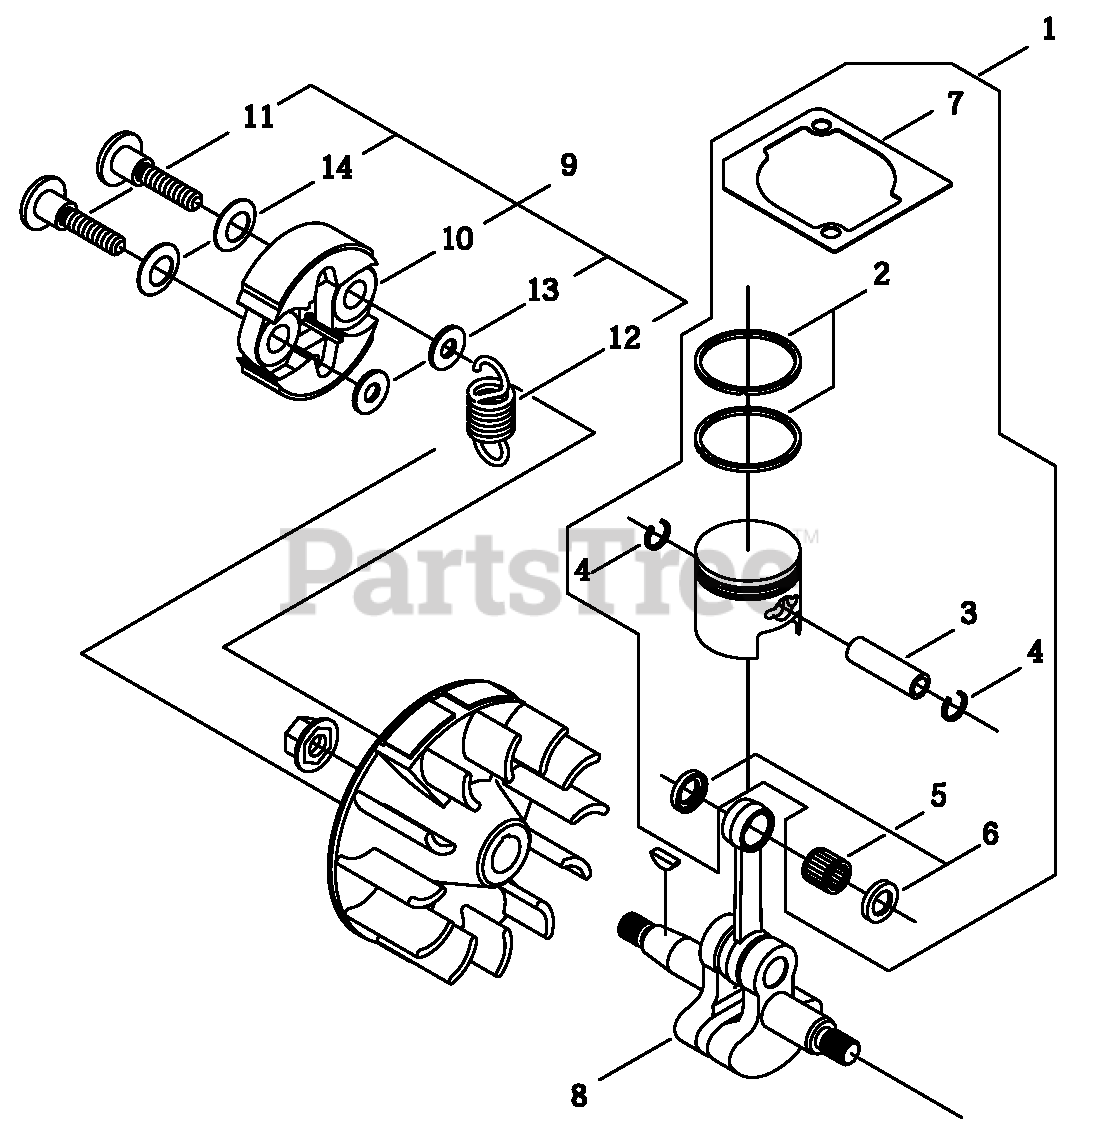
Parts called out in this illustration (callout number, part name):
1	PISTON ASSY
2	RING, PISTON
3	PIN, PISTON
4	RING, RETAINING
5	BEARING, NEEDLE - 8
6	SPACER, PISTON
7	GASKET, CYLINDER
8	CRANKSHAFT ASSY
9	CLUTCH ASSY
10	CLUTCH SHOE SET
11	BOLT, CLUTCH
12	SPRING, CLUTCH
13	WASHER - 6
14	WASHER - SPRING
